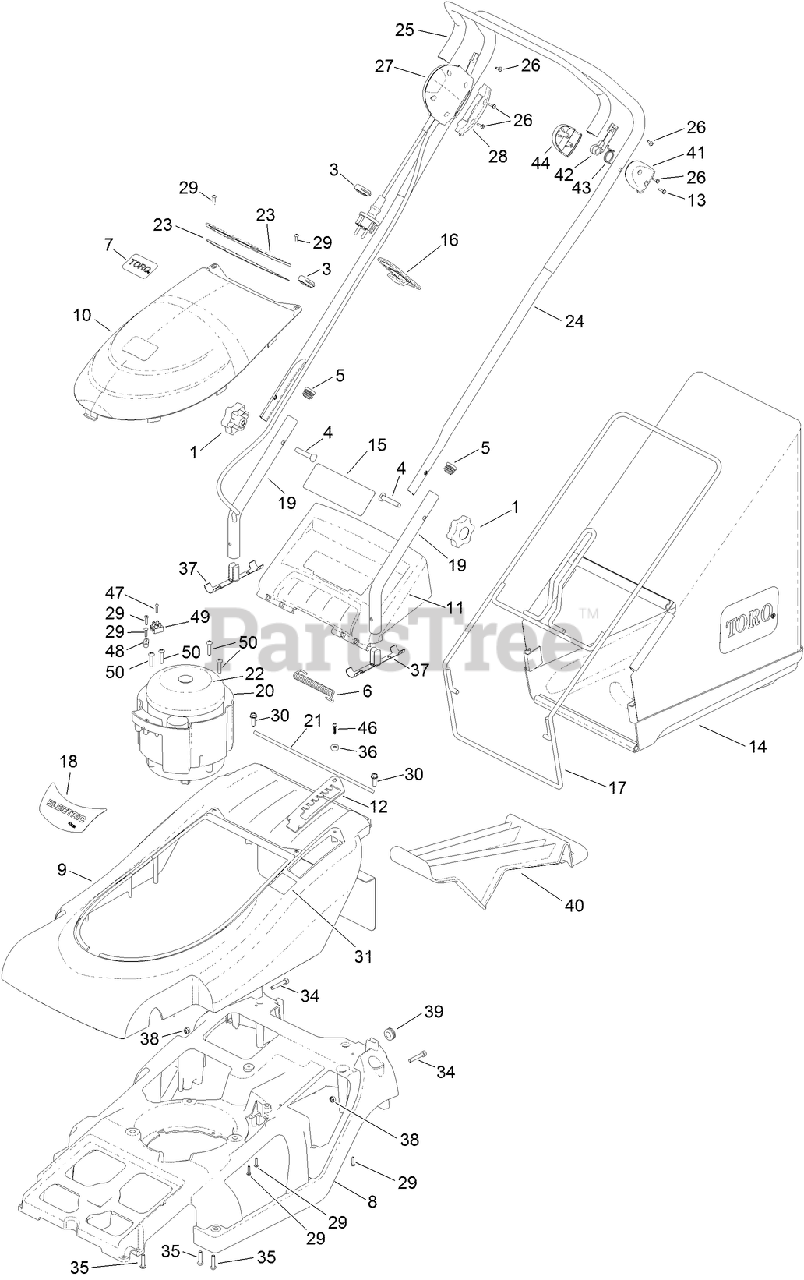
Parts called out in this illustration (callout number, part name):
1	KNOB-HANDLEBAR
3	CLIP-CABLE
4	BOLT-HANDLEBAR
5	PLUG-TUBE
6	SPRING-DEFLECTOR
7	DECAL-TORO
9	TOP-COVER
10	COVER-MOTOR
11	MOULDING-DEFLECTOR, REAR
12	PLATE-HOC
13	SCREW-PPH
14	GRASSBAG
15	DECAL-SAFETY, ELECTRIC
16	CLEAT-CABLE
17	FRAME-GRASSBAG
19	HANDLEBARS-LOWER
20	MOULDING-MOUNT, ELECTRIC MOTOR
21	BAR-HINGE
22	MOTOR-INDUCTION, 1.5KW
23	MOULDING-VENT, SUPPORT
24	HANDLEBARS-ELECTRIC
27	SWITCH AND LEAD ASM
28	SWITCH-LEFT, LOWER
30	SCREW-TAPTITE
31	DECAL-HOC
36	CUP-SCREW, ELECTRIC
37	PLUG-HANDLEBAR
38	NUT-NYLOC
39	GROMMET-RUBBER
40	PLUG-MULCHING
41	MOUNT-LEFT
42	LEVER-MOUNT
43	SPRING-BAILARM
44	MOUNT-RIGHT
46	SCREW-PLASTITE
48	CLAMP-CABLE
49	BLOCK-TERMINAL
